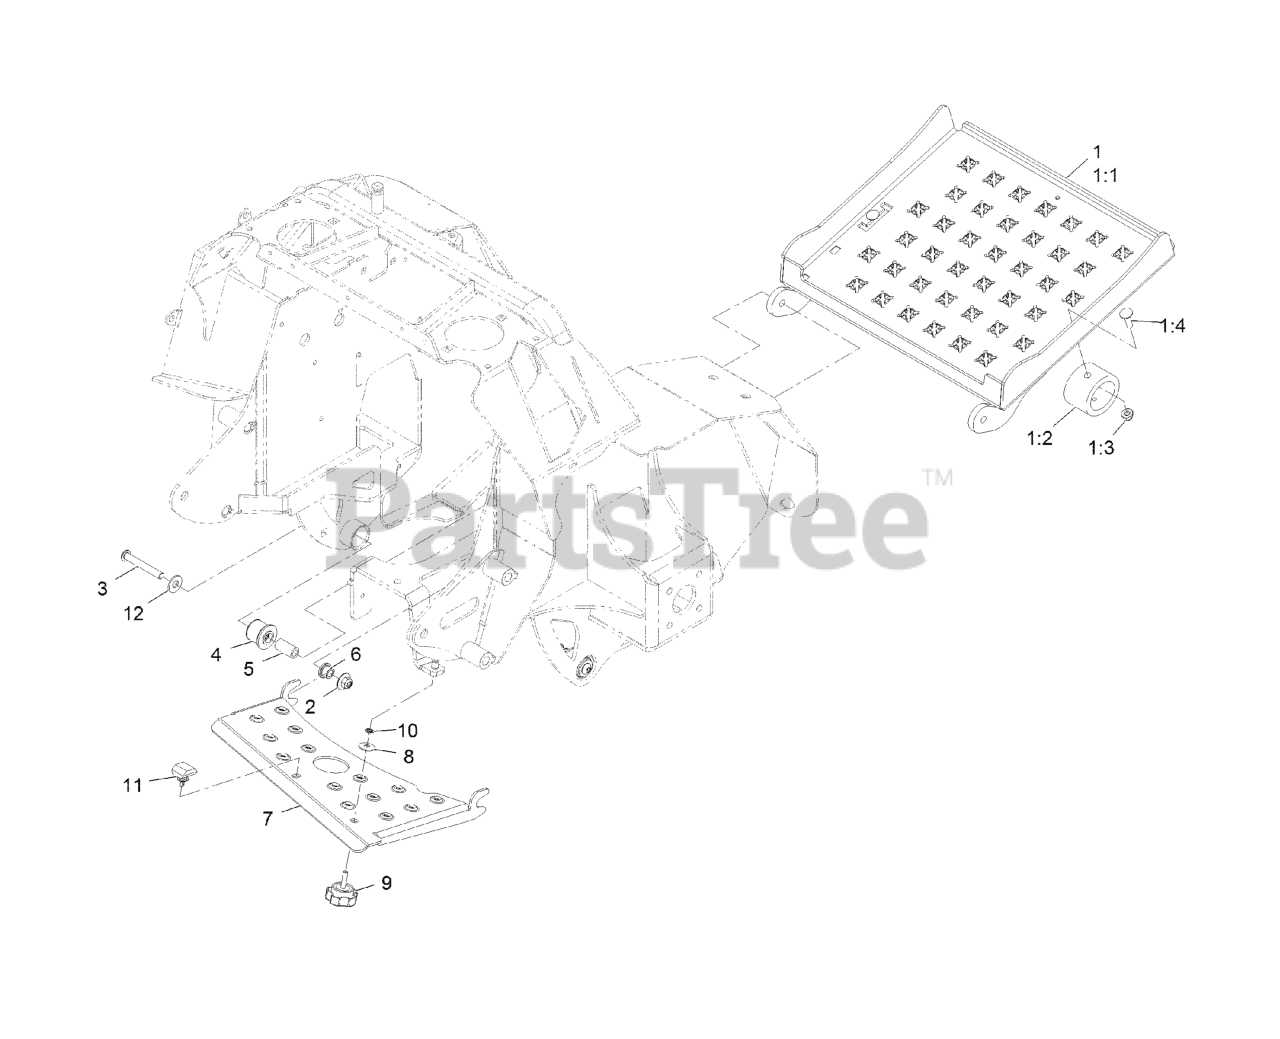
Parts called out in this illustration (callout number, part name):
1:2	BUMPER-ISOLATOR
1:3	NUT-HF, NI
1:4	BOLT-CARR
2	Nut-Nyloc 3/8-16 Flg
3	SCREW-HSBH
4	BUSHING-RUBBER, SUSPENSION
6	BUSHING-FLANGED
7	DEFLECTOR-AIR,44
8	WASHER-BELLEVILLE
10	NUT-RETAINING
11	BUMPER-ROPS
12	WASHER-FLAT
